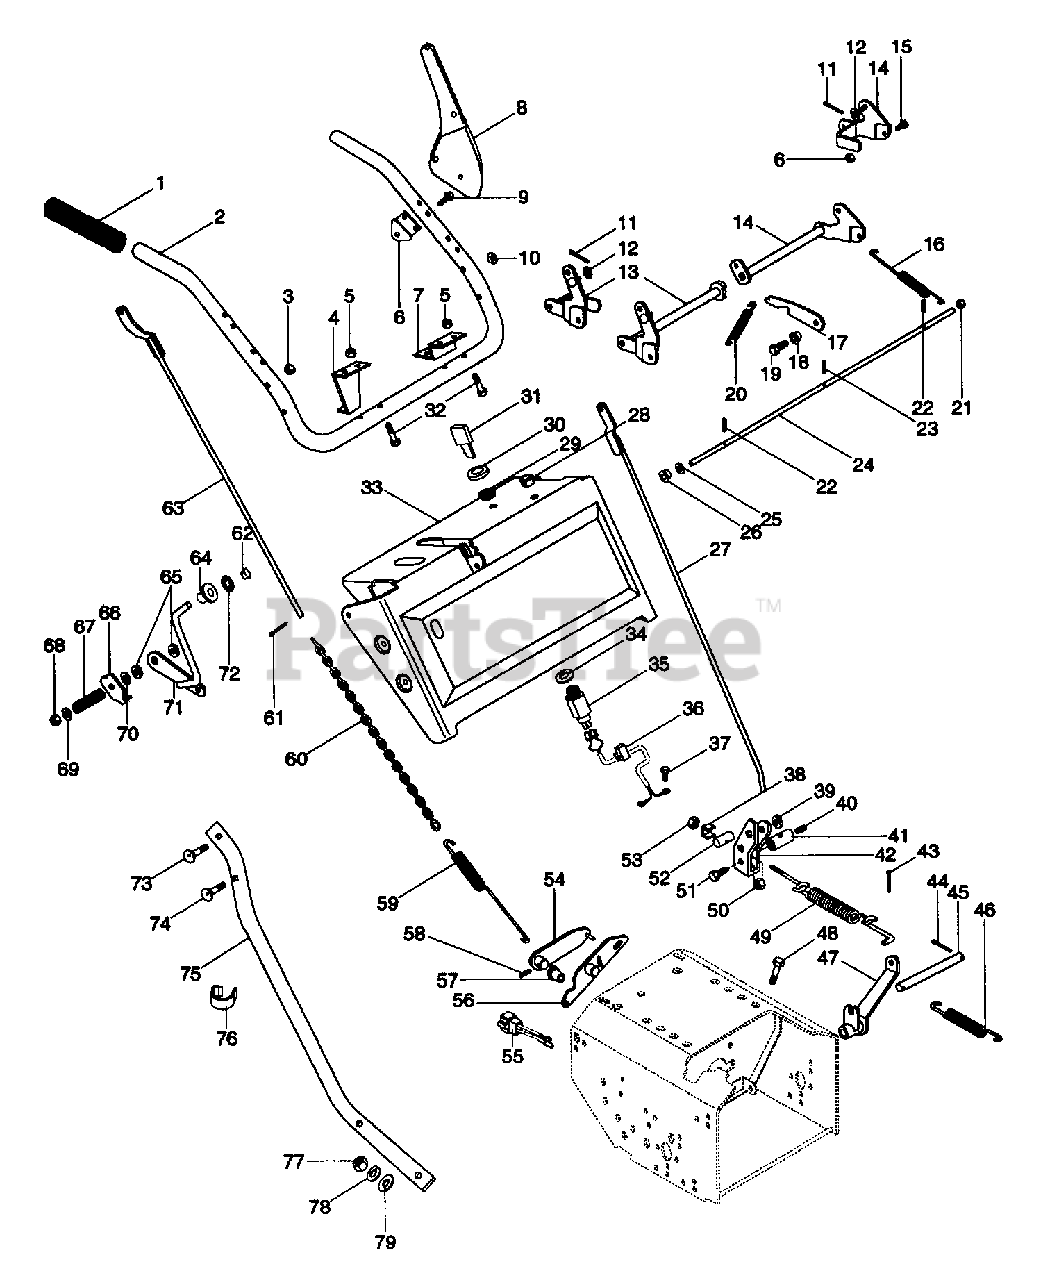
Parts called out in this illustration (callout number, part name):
1	HANDLE GRIP
2	UPPER HANDLEBAR
3	NUT-FLG. .312-18 PL
4	BRACKET, ROD
5	NUT-LK-CTR .250-20 PL
6	HANDLE PIVOT
7	BRACKET, CHUTE CRANK
8	CLUTCH LEVER - COATED
9	SCR-TAP 12-14X1.50 CROVH PL BT
11	PIN COTR .09X.50 PL
12	WSHR-FL-STL .268X.562X.046 PL
13	RH LEVER
13	R H LEVER
14	LH LEVER
14	L H LEVER
15	BLT-HEX .25-20X.38 PL GR2
16	SG-TENS .051X.50X5.12 WLD 10.4
17	ARM, LATCH
18	BSHG-FLG .265X.437X.329X1.00
19	BLT-HEX .25-20X.75 PL GR2
20	SG-TENS .048X.44X1.75 WLD 9
21	NUT-CROWN .312-18
22	PIN-ROLL .156X.75
23	PIN-ROLL .125X1.00
25	WSHR-FL-STL .323X.625X.062 PL
26	BSHG-FLG .325X.465X.333X.685
27	TRACTION CLUTCH ROD
28	SNAP BUSHING
29	NUT-PANEL .625-32 GRECO
30	CAP - IGNITION SWITCH
31	KEY -W/CAP
32	BLT-HEX .25-20X1.25 PL GR5
33	PANEL W/DECAL
34	WSHR-LK-INT .625X.045 PL
35	SWITCH ASSEMBLY
36	SHORTING WIRE
37	SCR-TAP .250-20X.37 HWH PL TR
38	ADAPTER SPACER
39	SPACER 1.00 X .64 X .38
40	SCR-SET .32-18X.38 SKHCUPNL OH
41	ROD ADAPTER
42	CLUTCH ENGAGEMENT YOKE
43	PIN-COTR .09X.75 PL
44	PIN-COTR .09X1.0 PL
45	ROD, FORK PIVOT
46	SG-TENS .080X.73X3.06 WLD 20
47	FORK, CLUTCH
48	BLT-HEX .38-16X1.00 PL
49	SPRING ASSEMBLY
50	NUT-LK .312-18 GR A PL
51	BLT-HEX .31-18X.75 PL GR2
52	ADAPTER
53	NUT-LK-NYL.312-18 PL
54	LEVER CLUTCH
55	JUMPER
57	BSHG-FLG.500X.625X.312X.750NY
58	PIN-ROLL .156X.88
59	SG-TENS .091X.56X6.12 WLD 40
60	CLUTCH CHAIN
61	PIN-COTR .12X.75 PL
62	HOLE PLUG
63	ATTACHMENT CLUTCH ROD
65	FRICTION WASHER
66	PRESSURE FLANGE
67	SG-COMP .187X.56X1.62
68	NUT-LK-CTR .375-16 GR A PL
69	WSHR-FL-STL.406X.812X.065PL
70	SPACER .406X.620X.125
71	LEVER-DEFLECTOR
72	RG-RTNG-EXT .375X.010
73	BLT-RDHDSQNK .31-18X1.50 PL
74	BLT-RDHDSQNK .31-18X2.75 SHPL
75	L H LOWER HANDLEBAR
75	R H LOWER HANDLEBAR
77	NUT-HEX .375-16
78	WSHR-LK .375X.115 HVY PL
79	WSHR-FL-STL .438X1.0X.083 PL
